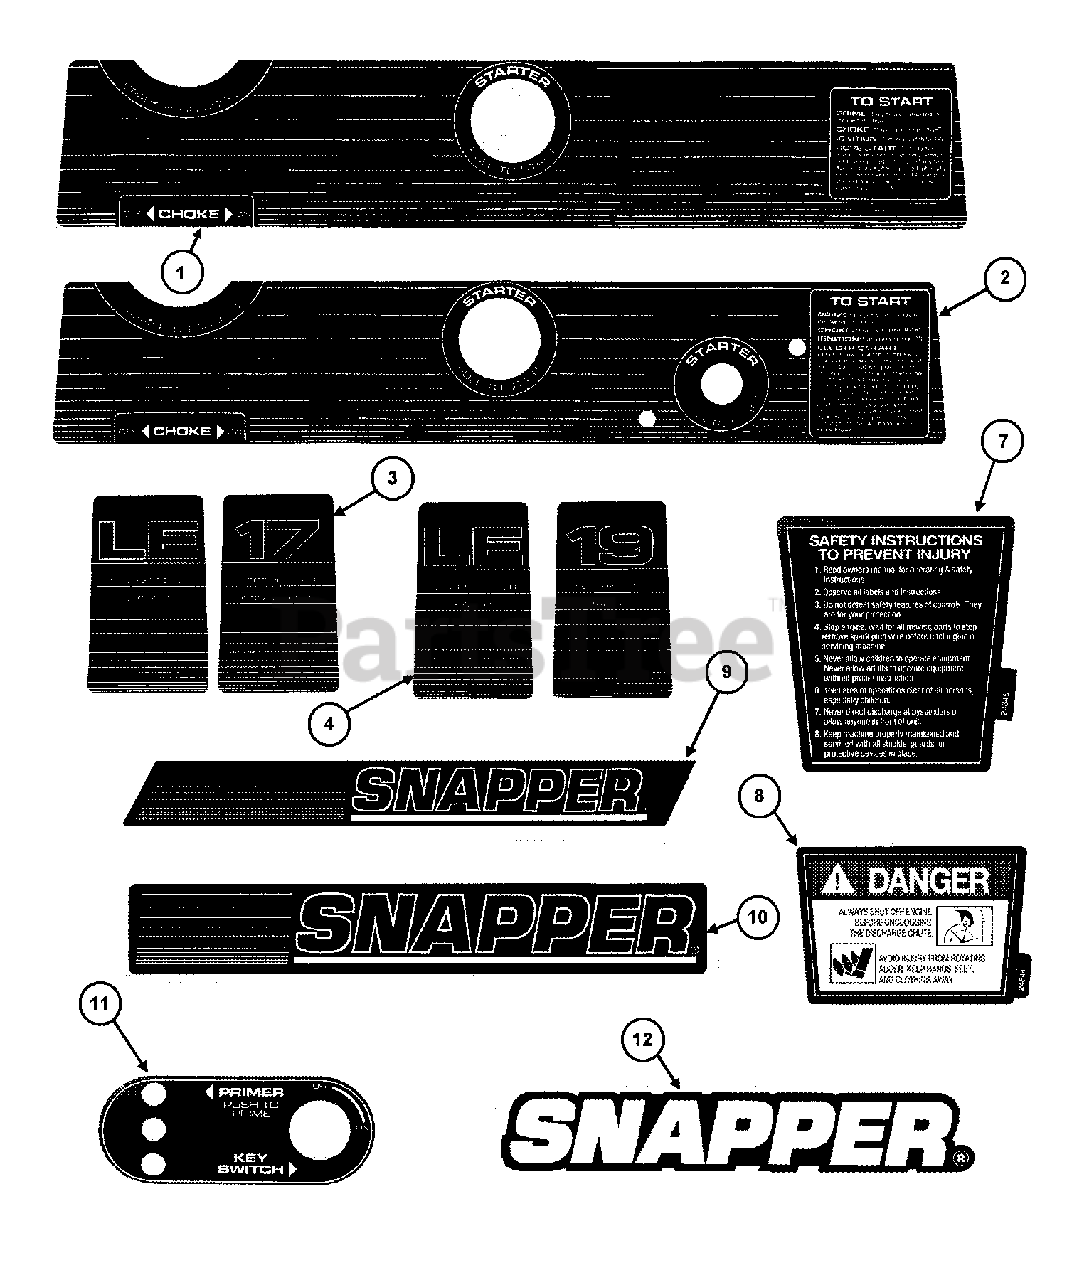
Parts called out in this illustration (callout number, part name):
1	DECAL, Panel Instructions
2	DECAL, Panel Instructions
3	DECAL, 17" Models
4	DECAL, 19" Models
7	DECAL, Safety Instruction
8	DECAL, Danger
9	DECAL, SNAPPER (Top Cover)
10	DECAL, SNAPPER (Belt Cover)
11	DECAL, Primer Instruction
12	LOGO, SNAPPER
